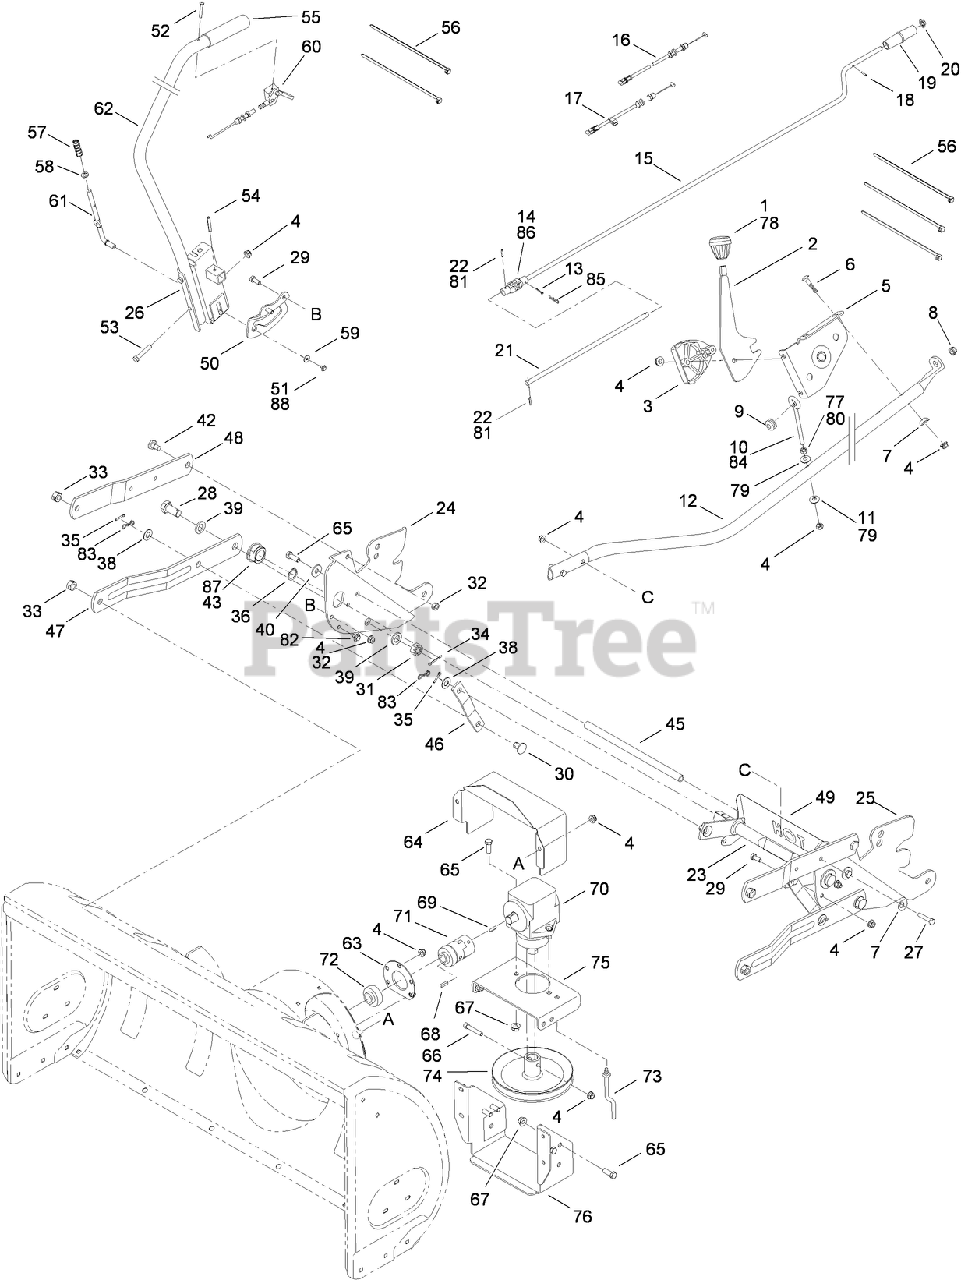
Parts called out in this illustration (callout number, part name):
2	HANDLE-TILT, CHUTE
3	GUIDE-CABLE
4	NUT-LOCK, FLANGE
5	BRACKET-TILT, CHUTE
6	BOLT-CARR
7	WASHER-SADDLE
8	BUSHING
9	GROMMET
10	EYEBOLT
11	WASHER-BELL
12	TUBE-SUPPORT, CHUTE
13	PIN-COTTER
14	JOINT BLOCK ASM
15	ROD-CRANK, CHUTE
16	CABLE-CHUTE
17	CABLE-CHUTE
18	PIN-ROLL
19	KNOB-CRANK, CHUTE
20	NUT-PUSH
22	PIN-SPRING, SPIRAL
23	ROD ASM
24	RH SUPPORT PLATE ASM
25	LH SUPPORT PLATE ASM
26	LIFT BRACKET ASM
27	SCREW-HH
28	SCREW-HH
29	SCREW-HH
30	PIN-BRACKET, LIFT
31	NUT-HEX CASTLE
32	NUT-LOCK
33	NUT-HEX, LOCK
34	PIN-COTTER
35	PIN-COTTER
36	RING-SNAP
38	WASHER-FLAT
39	WASHER-FLAT
40	WASHER-BELL
42	BOLT-SHOULDER
43	BEARING-FLANGE
49	SHIELD-HEAT
50	BRACKET-LIFT
51	SCREW-HH, TAP
52	SCREW-PAN HD
53	BOLT-HH
54	PIN-ROLL
56	TIE-CABLE
57	SPRING-COMPRESSION
58	WASHER-FLAT
59	WASHER-FLAT
60	CABLE-LIFT, W/TRIGGER
61	ROD-INDEX, LIFT
62	TUBE-HANDLE, LIFT
63	HOUSING-BEARING
64	COVER-BELT
65	SCREW-HH
66	SCREW-HSH
67	NUT-LOCK, FLANGE
68	KEY-SQUARE
69	KEY-HI PRO
70	DRIVE-ANGLE, RIGHT
71	COUPLER-FLEXIBLE
72	BEARING-BALL (W/OUT COLLAR)
73	ROD-KEEPER, BELT
74	PULLEY-DRIVE
75	BRACKET-MOUNTING
76	PLATE-SKID
77	NUT-HEX
79	WASHER-SPRING
80	NUT-HEX
81	PIN-SPIROL
82	SCREW-HWH
83	PIN-COTTER, BOW TIE
84	BOLT-EYE
85	PIN-COTTER
86	JOINT BLOCK ASM
87	BEARING-FLANGE
88	SCREW-WASHER, HEX INDEX
